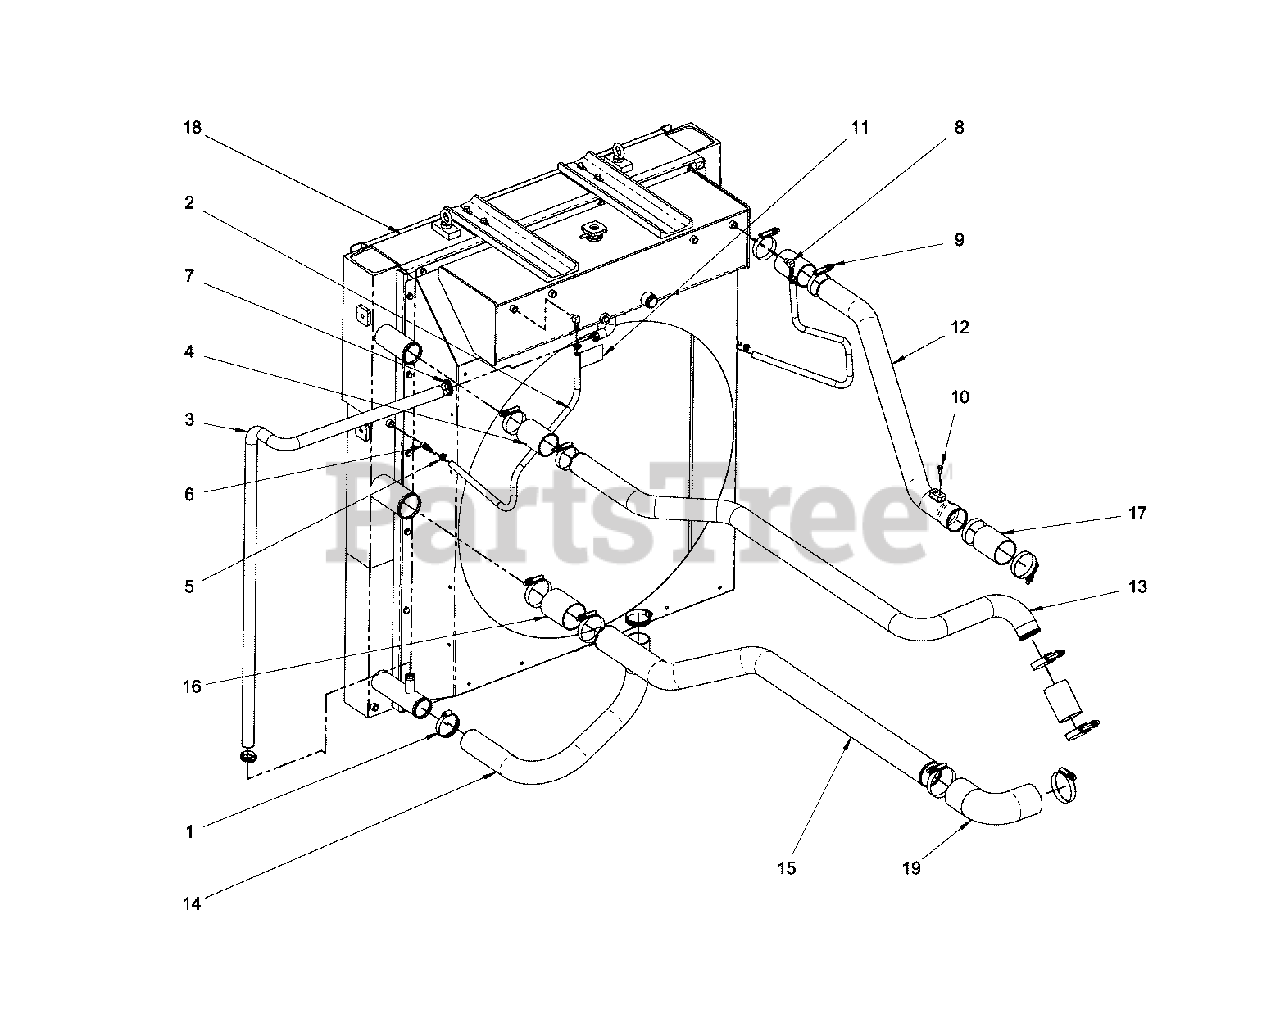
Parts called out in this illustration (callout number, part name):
1	CLAMP
2	* HOSE - 48 IN
3	HOSE - 100 IN
4	HOSE
5	CLAMP
6	- FITTING
7	CLAMP
8	FITTING
9	CLAMP
10	* BOLT
11	* STICKER
12	TUBE
13	TUBE
14	HOSE
15	* INLET PIPE
16	HOSE
17	HOSE
18	RADIATOR
19	HOSE
